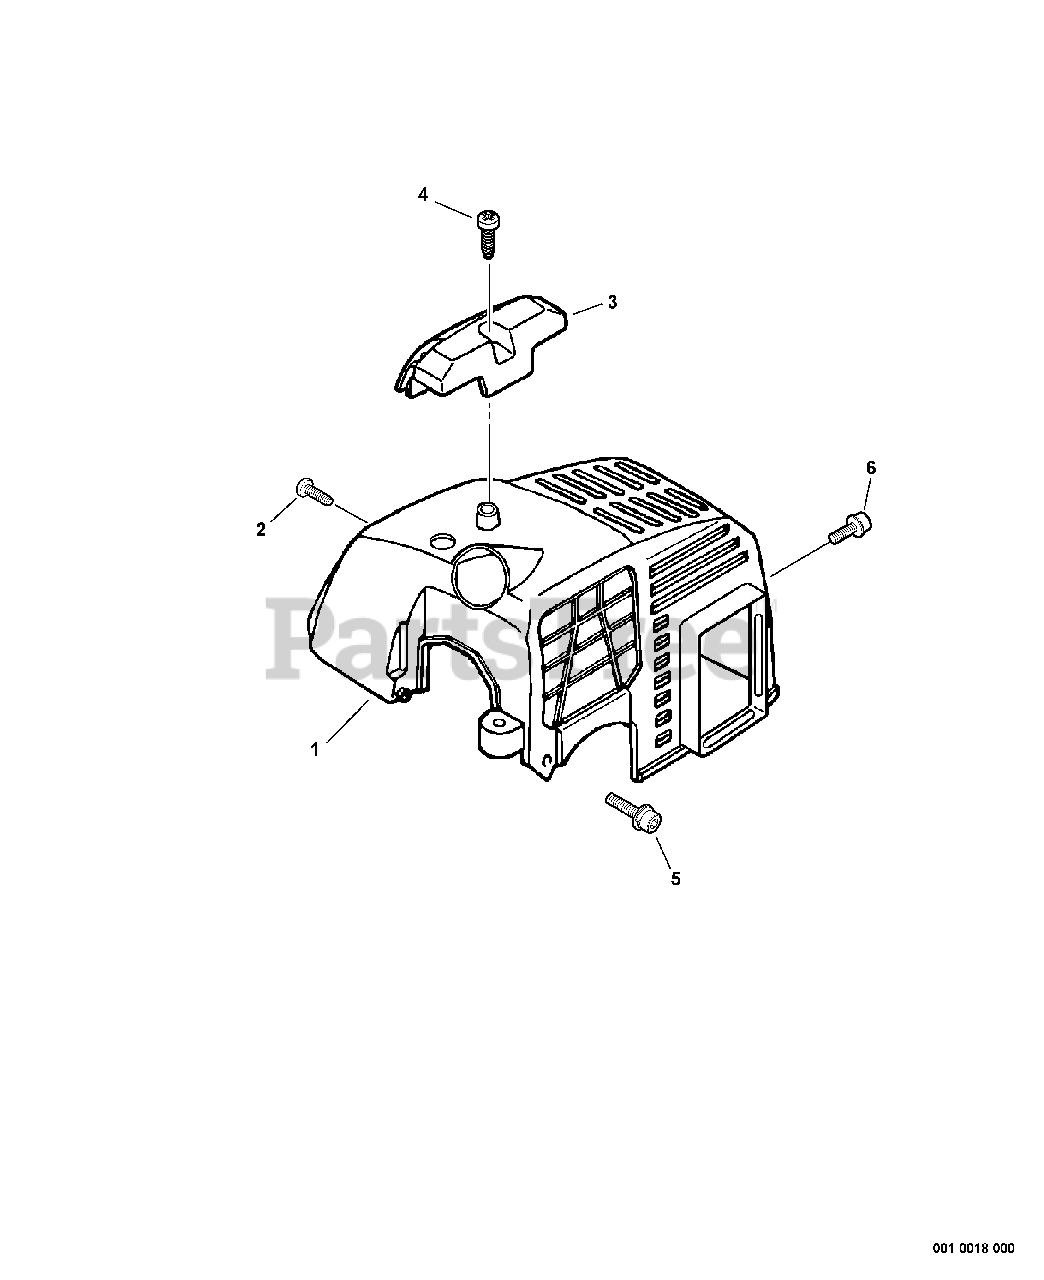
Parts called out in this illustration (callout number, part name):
1	COVER, ENGINE
2	SCREW 4×12
3	GUARD, TOP
4	SCREW 5×16
5	BOLT 4×16
6	SCREW - 4×8
